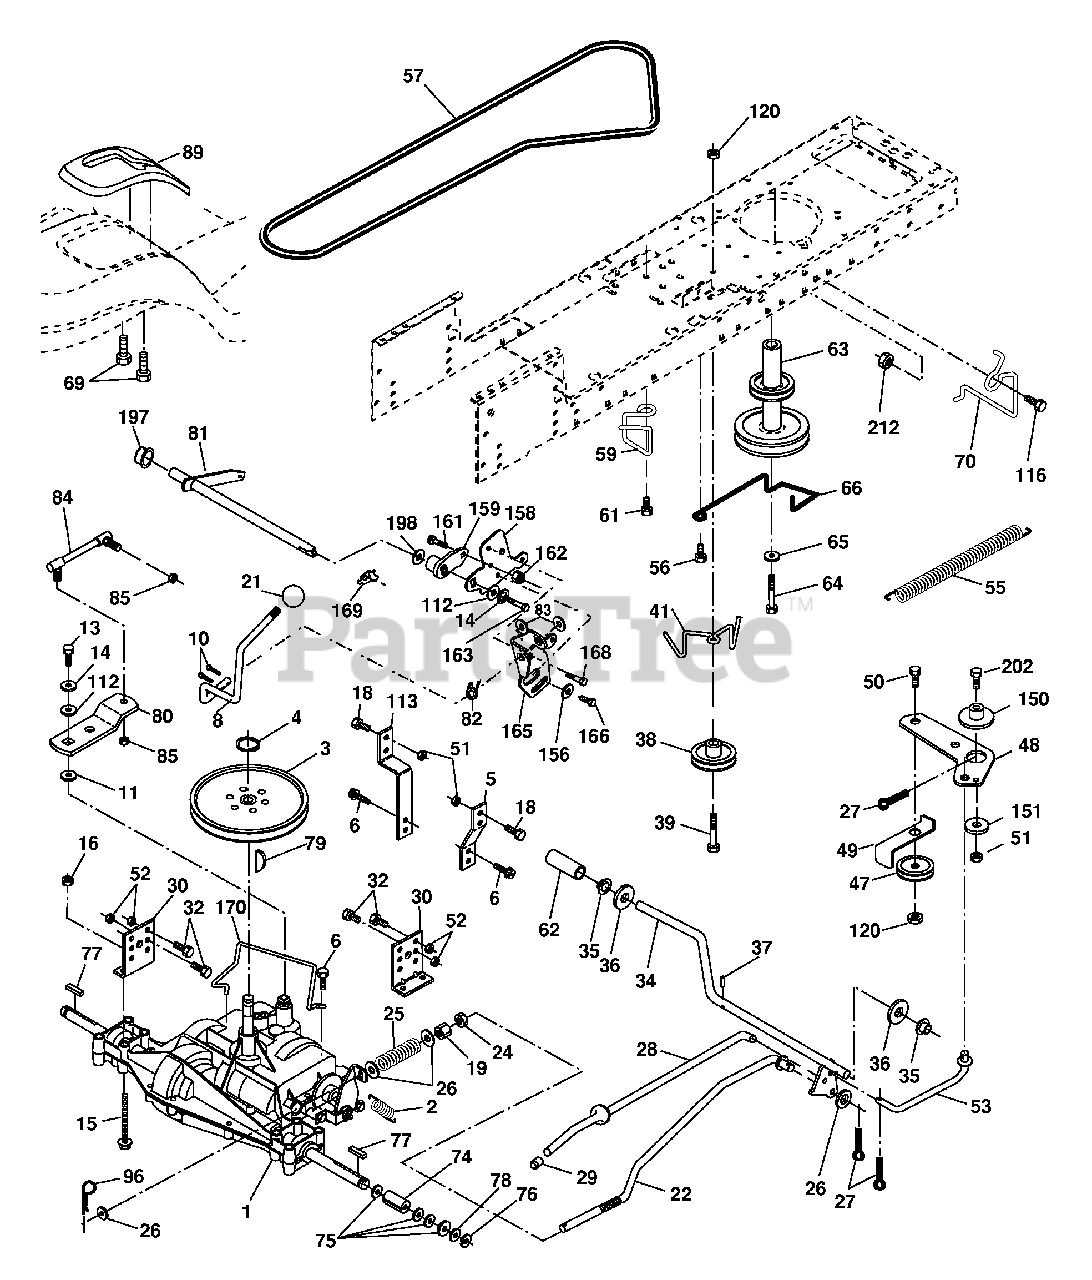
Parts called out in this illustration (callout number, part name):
2	Spring Brake Return
3	Pulley Transaxle
4	Ring Retainer
5	Strap Torque 30 Degrees
6	Screw 5/16-18 x 3/4
8	Rod Shift Fender Adjust
10	Pin Cotter 1/8 x 1 CAD
11	Washer Plate Shift
13	Bolt 1/4-28unf Gr. 8 W/Patch
14	Washer Lock Hvy Helical
15	Bolt Hex FLGHD 5/16-18 Gr. 5
16	Nut Lock Hex W/Ins 5/16-18 UNC
18	Bolt Fin Hex 3/8-16 UNC x 1 Gr 5
19	Nut Lock Hex W/Ins 3/8-16 UNC
21	Knob
22	Rod, Brake
24	Nut, Hex Jam 3/8-16 unc
25	Spring, Brake Rod
26	Washer 13/32 x 13/16 x 16 Ga.
27	Pin Cotter 1/8 x 3/4 CAD.
28	Rod, Parking Brake
29	Cap, Parking Brake
30	Bracket, Transaxle
32	Bolt Hex Hd 5/16-18 UNC x 3/4
34	Shaft, Foot Pedal
35	Bearing, Nylon
36	Washer
37	Pin, Roll
38	Pulley, Composite, Flat
39	Bolt RDHD 3/8-16 UNC x 1 Gr. 5
41	Keeper, Belt Idler
47	Pulley, Idler, V-Groove
48	Bellcrank, Clutch
49	Retainer, Belt
50	Bolt Hex Hd 3/8-16 x 1-1/2
51	Nut Crownlock 3/8-16 unc
52	Nut, Crownlock 5/16-18 unc
53	Link, Clutch
55	Spring, Return, Clutch
56	Screw 3/8-16 x 1.04
57	V-Belt
59	Keeper, Center Span
61	Screw. 3/8-16 x .875
62	Cover, Pedal
63	Pulley, Engine
64	Bolt Hex 7/16-20 x 4 x Gr. 5
65	Washer Lock
66	Keeper Belt Engine Hydro
69	Screw Hex Wsh Hi-Lo 1/4 x 1/2 unc
70	Keeper Belt Engine
74	Spacer
75	Washer 25/32 x 1-1/4 x 16 Ga.
76	E-Ring
77	Key, Square
78	Washer 25/32 x 1-5/8 x 16 Ga.
79	Key Woodruff
80	Arm Shift
81	Shaft Asm Cross Tapered
82	Spring Torsion
83	Washer 17/32 x 3/4 x 16 Ga.
84	Link Transaxle
85	Nut Lock Center 1/4-20
89	Console, Shift
96	Retainer Spring 1" Zinc/Cad
112	Washer 9/32 x 3/4 x 10 Ga.
113	Strap Torque 90 Degrees
116	Bolt Rdhd Sqneck 3/8-16 x 1.25
120	Nut Lock Flg 3/8-16
150	Spacer Retainer
151	Washer 13/32 x 2 x 10 Ga.
156	Washer Srrted 5/16ID x 1.125
158	Bracket Shift Mount
159	Hub Tapered Flange Shift Lt
161	Bolt Rdhd Sqnk 1/4-20 x 3/4 Gr 5
162	Nut Crownlock 1/4-20 unc
163	Bolt Hex Fin 1/4-20 unc x 1 Gr 5
165	Bracket Pivot Lever
166	Screw 5/16-18 x 5/8
168	Bolt Shoulder 5/16-18 x .561
169	Plate Fastening
170	Keeper Belt T/A
197	Nyliner Snap-In 5/8"ID
198	Washer Nyl
202	Bolt Carr Sh 3/8-16 x 1-3/4 Gr.5
212	Nut Hex Flg. Lock
